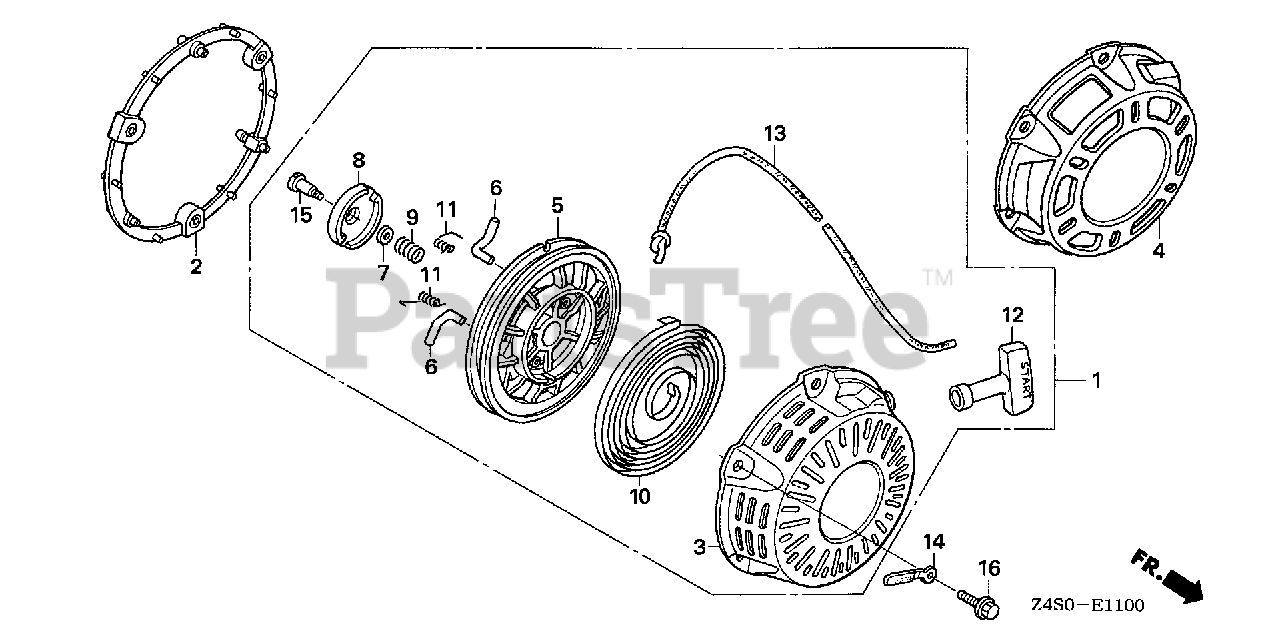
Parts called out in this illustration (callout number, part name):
1	STARTER ASSY., RECOIL *R280* (POWER RED)
2	SPACER, RECOIL STARTER MOUNTING *R280* (POWER RED)
3	CASE, RECOIL STARTER *R280* (Honda Code 7346836). (POWER RED)
5	REEL, RECOIL STARTER
6	RATCHET, STARTER
7	PLATE, FRICTION
8	GUIDE, RATCHET
9	SPRING, FRICTION
10	SPRING, RECOIL STARTER
11	SPRING, RETURN
12	GRIP, STARTER
13	ROPE, RECOIL STARTER (#5X55")
15	SCREW, SETTING
16	BOLT, FLANGE (6X18)
